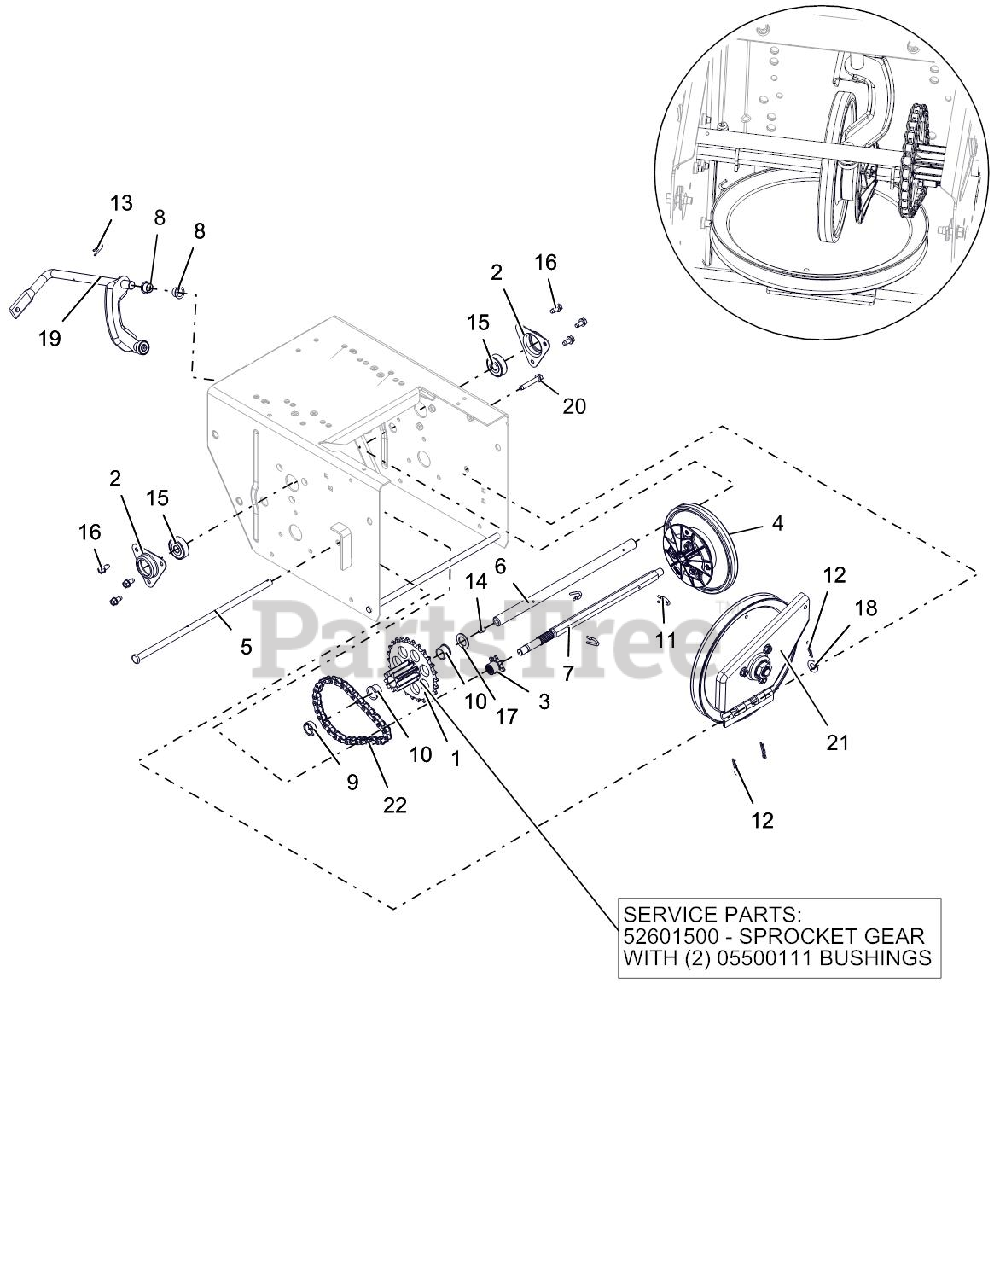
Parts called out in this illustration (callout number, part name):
1	BSHG-FLG .625X.750X.500X.875
1	PINION & SPROCKET
1	PINION & SPROCKET W/BUSHINGS
2	FLANGE, BEARING
3	SPROCKET, PINION 7T W/SPLINE
4	DISC, FRICTION DRIVE-ASSEMBLY
5	PIN, PIVOT
6	SHAFT, PINION
7	SHAFT, HEX
8	BUSHING, POLYLINER-.50 SPLIT
9	BSHG-SLV, .635X.880X.305
10	BSHG-FLG .625X.750X.500X.875
11	PIN, SPRING CLIP
12	PIN-HAIR, ENDRIES #25 YWZC
13	CLIP, SPRING
14	ZERK,FITTING .25X.125 DRIVE IN
15	BRG-BALL .437X1.375X.437
16	SCR-TAP .25-20X.50 HWH TR YWZ
17	WSHR-FL-STL .630X1.005X.062 YZ
18	@WSHR-FL-STL.406X.812X.065 YWZ
19	ARM, SHIFT - ASSEMBLY
20	@SCR-TAP .25-20X1.50 HWH TR YZ
21	PLATE, SWING ASSEMBLY-DEEP
22	CHAIN - #41, 32 PITCHES
